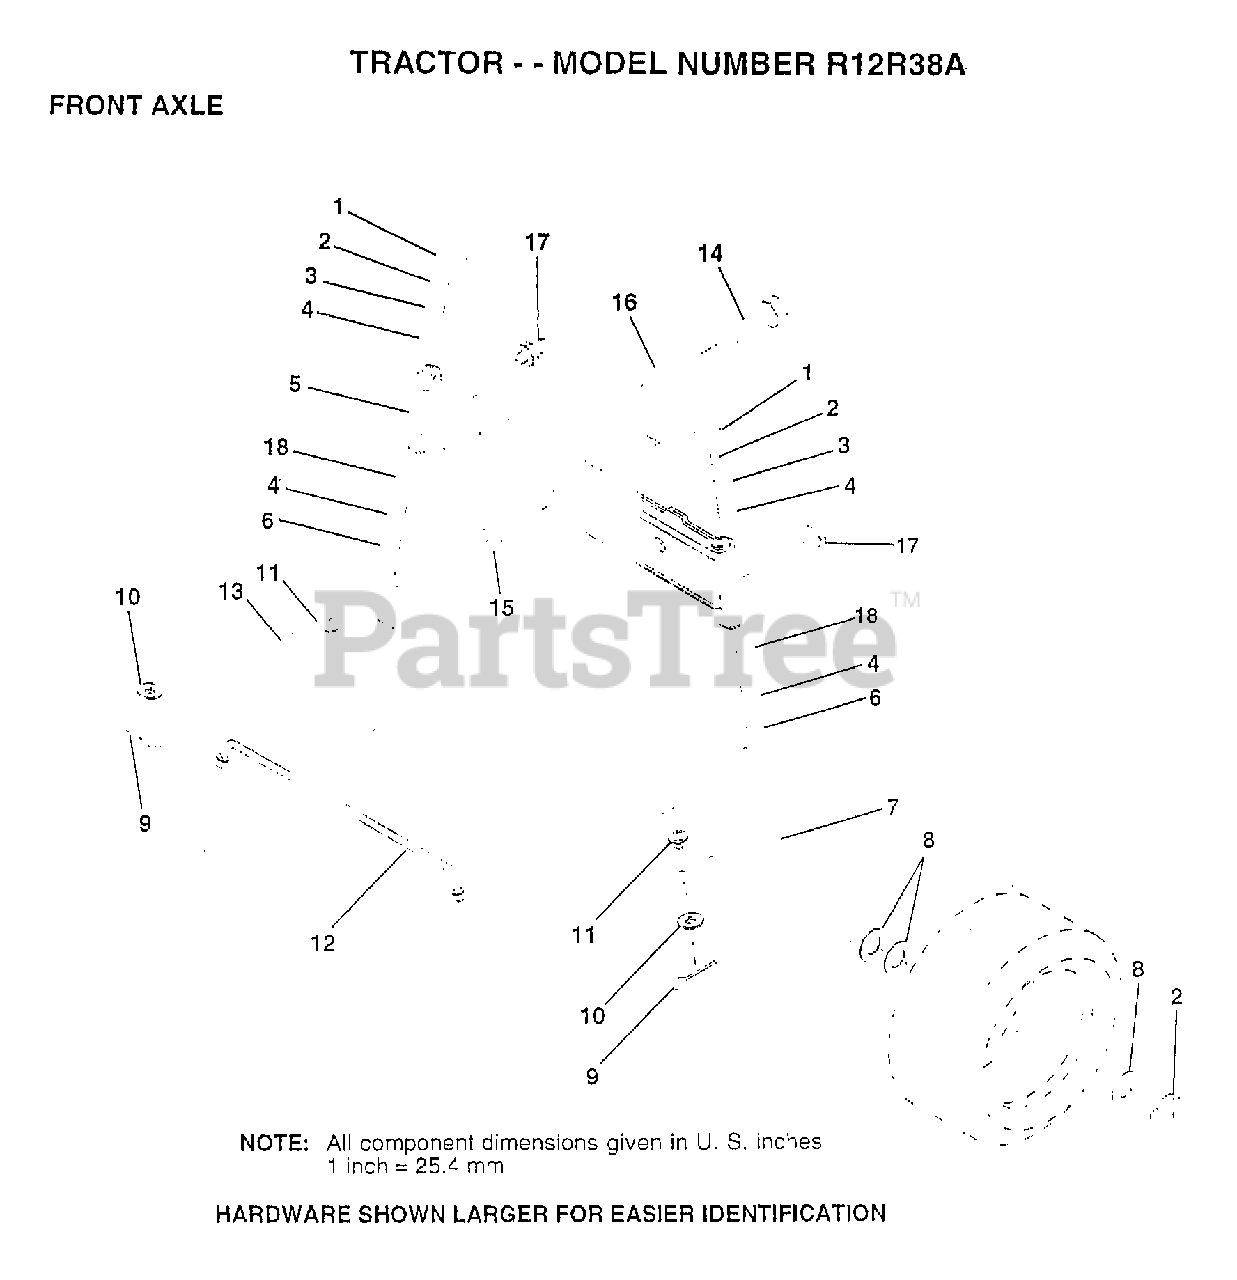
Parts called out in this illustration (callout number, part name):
1	CAP
2	RING
3	WASHER
4	COL. SRTG. BEAR.
5	AXLE ASM FRONT
6	WASHER .T
7	SPINDLE ASM RH
8	WASHER
9	COTTER PIN
10	WASHER
11	BUSHING.DRAGLINK
12	TIE ROD
13	SPINDLE ASM LH
14	BOLT HEX 5/8-11
15	"NUT-LOC,FLANGE LT"
16	SPACER, BEARING, FRONT AXLE
17	ZERK M
18	WASHER
